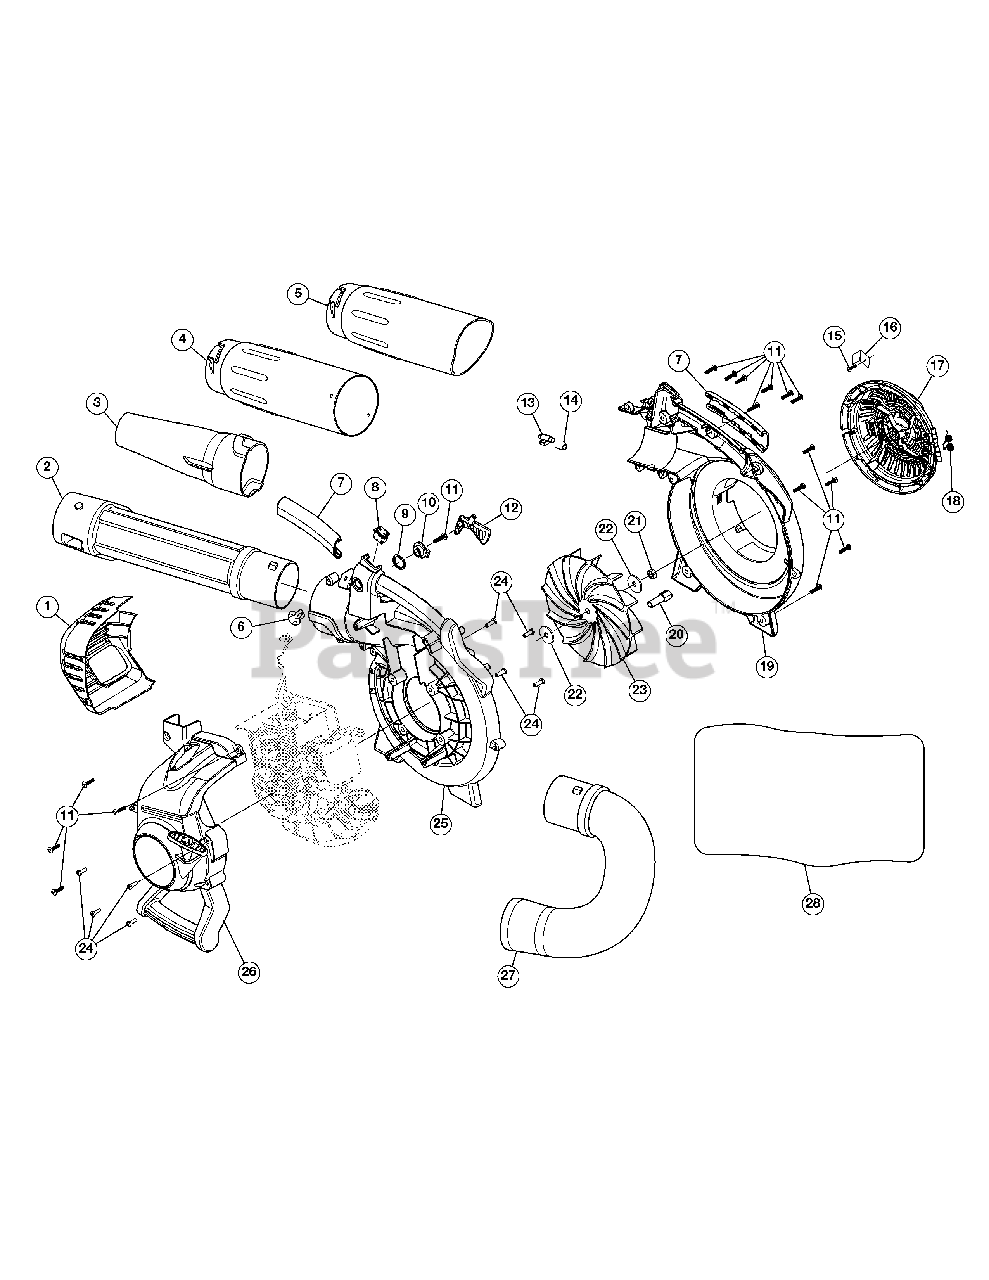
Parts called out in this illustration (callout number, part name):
1	Muffler Cover Assembly (Incl. 11)
2	Upper Tube
3	Lower Tube
4	Upper Vac Tube
5	Lower Vac Tube
6	Outer Trigger Lock
7	Handle Grips
9	Wavey Washer
10	Inner Trigger Lock
12	Throttle Trigger
13	Latch Tube
14	Latch Spring
15	Screw
16	Door Lock
17	Intake Cover
18	Spring
19	Impeller Housing
20	Adapter
21	Nut
22	Washer
23	Impeller
24	Screw
25	Impeller Housing
26	Engine Cover Assembly (Incl. 11 & 24)
